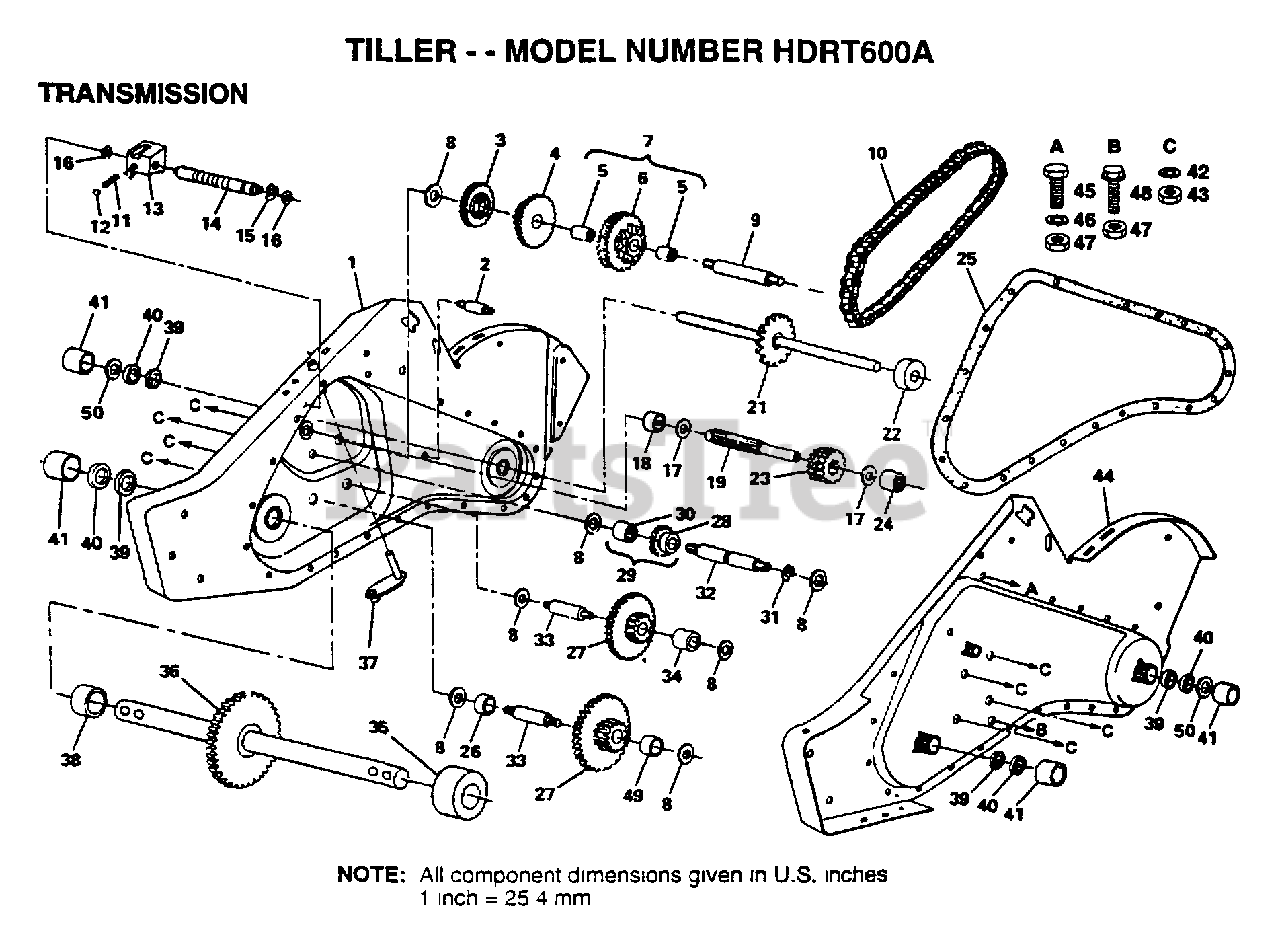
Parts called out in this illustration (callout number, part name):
2	BOLT TI
3	REVERSE GEAR TI
4	CLUSTER GEAR TI
5	"CRT, BEARING"
7	SPROCKET ASSY TI
8	WASHER
9	REDUCTION SHFT TI
10	CHAIN TI
11	SPRING-SHIFT CRT
13	SHIFT FORK TI
14	SHIFT SHAFT TI
15	KLIP RING
16	WASHER SEAL CRT
17	"T, BEARING"
18	"TI, BEARING"
19	SHAFT INPUT T
21	SHAFT TINE CRT
22	SPACER CRT
23	INPUT PINION TI
24	NEEDLE BRNG LT
25	GEARCASE GSKT TI
26	SPACER CRT
27	GEAR CLUSTER CRT
28	REVERSE GEAR TI
29	GEAR ASSY TI
30	NEEDLE BEARING TI
31	KLIP RING
32	REVERSE SHAFT TI
33	SHAFT CRT
34	SPACER CRT
35	SPACER CRT
36	SHAFT ASSY CRT
37	BRACKET ASM SHIFT
38	SPACER CRT
39	OIL SEAL STD
40	SEAL RING RUBBER
41	CUP.FORMED.
42	LOCKWASHER
43	NUT.ASF.HEX.7/16
45	BOLT
46	LOCKWASHER
47	NUT.HEX.5/16-18
48	BOLT TI
49	SPACER CRT
50	RING SPIRAL CRT
